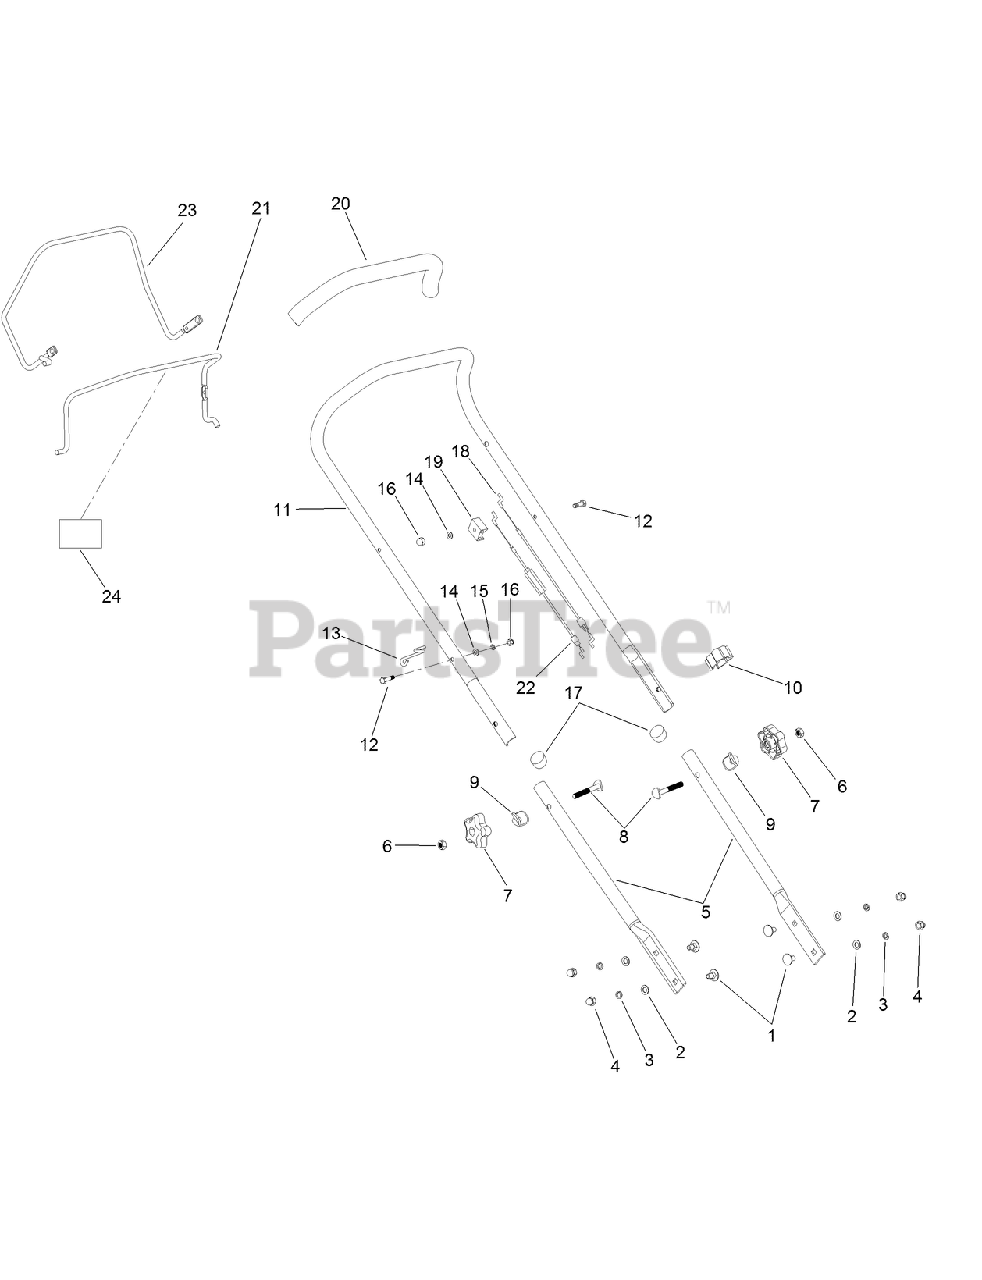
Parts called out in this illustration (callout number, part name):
2	WASHER
3	WASHER-SPRING
4	NUT-LID
5	HANDLEBAR-LOWER
6	NUT-HEX
7	KNOB-ROTARY
8	BOLT-FLAT HEAD
9	WASHER-CURVE
10	CABLE CLAMP
11	HANDLEBAR-UPPER
12	BOLT-HH, FLANGE
13	HOOK-CABLE
14	WASHER-PLAIN
15	WASHER-SPRING
16	NUT-LID
17	PLUG-TUBE
18	CABLE-BRAKE, ENGINE
19	CABLE-BLOCK, FIXED
20	GRIP-HANDLE
21	LEVER-ENGINE
22	CABLE-CLUTCH
23	LEVER-CLUTCH, GEARBOX
24	DECAL-STOP
